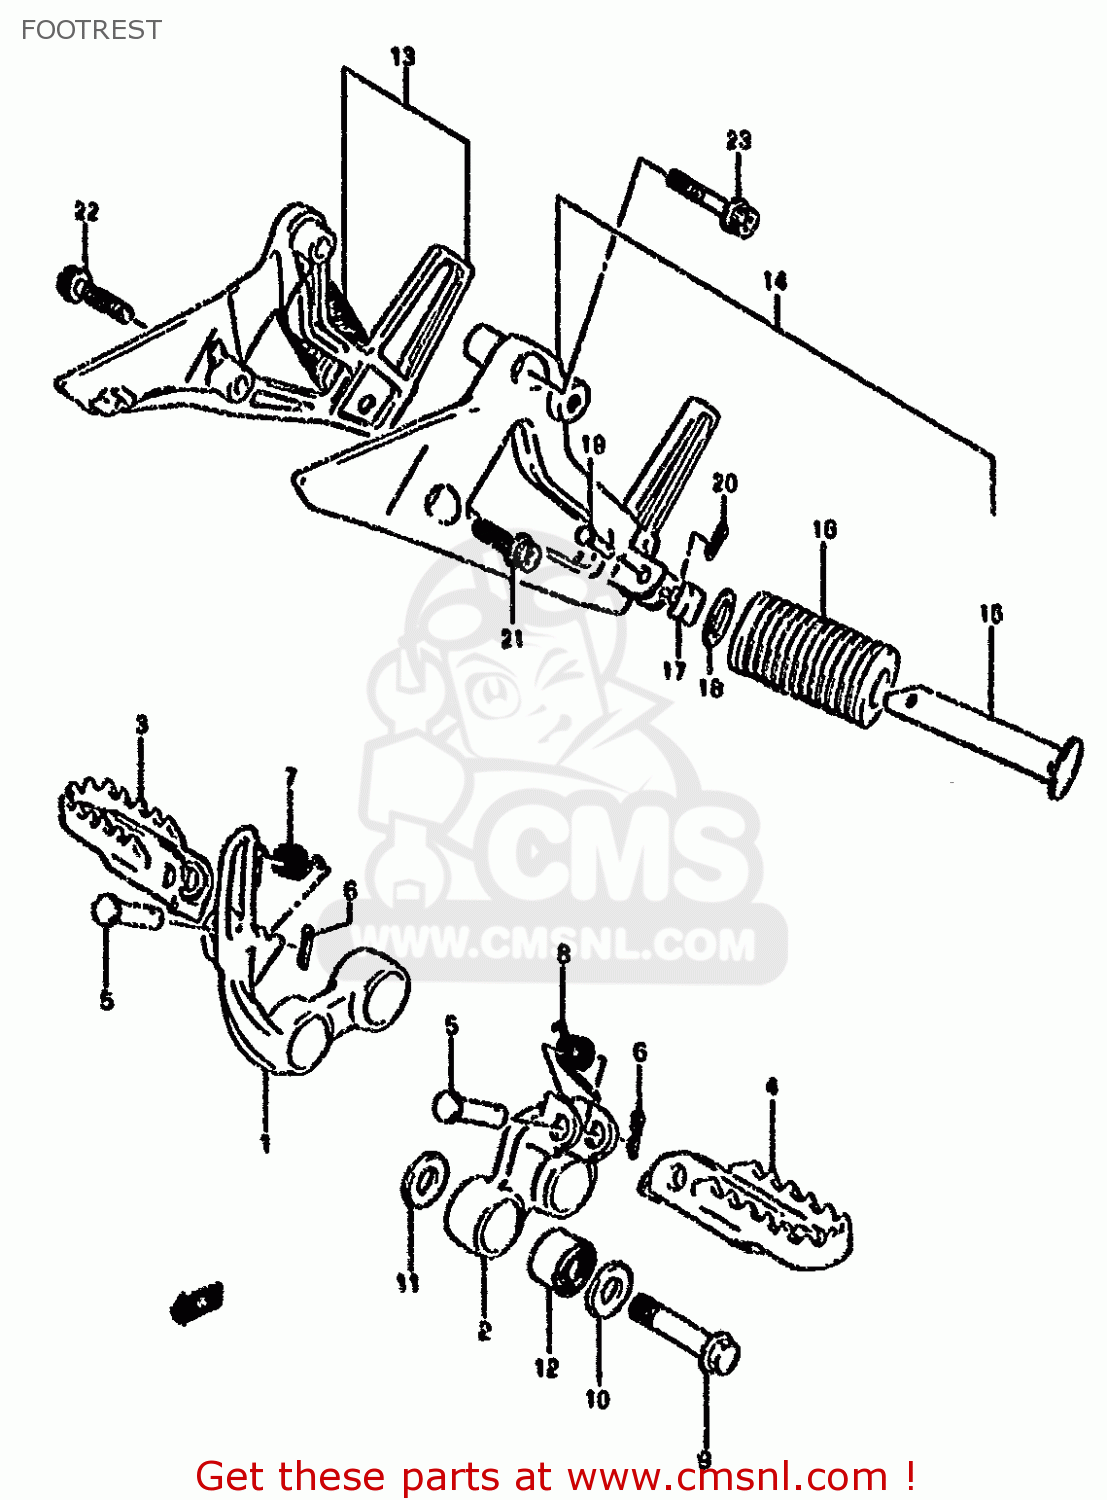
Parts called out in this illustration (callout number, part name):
1	BRACKET,FR FOOTREST,R
2	BAR, FOOTREST LH (BLACK)
3	FOOTREST,FR,R
4	FOOTREST,FR,L
5	PIN
6	PIN 20X20
7	SPRING
8	SPRING
9	BOLT(10X57)
10	WASHER
11	WASHER
12	BUSH
13	FOOTREST ASSY,PILLION,R
14	FOOTREST ASSY,PILLION,L
15	BAR,PILLION FOOTREST
16	RUBBER,PILLION FOOTREST
17	CUSHION
18	WASHER (19.5X32X2)
19	PIN
20	PIN
21	BOLT
22	BOLT(8X30)
23	BOLT(8X40)
